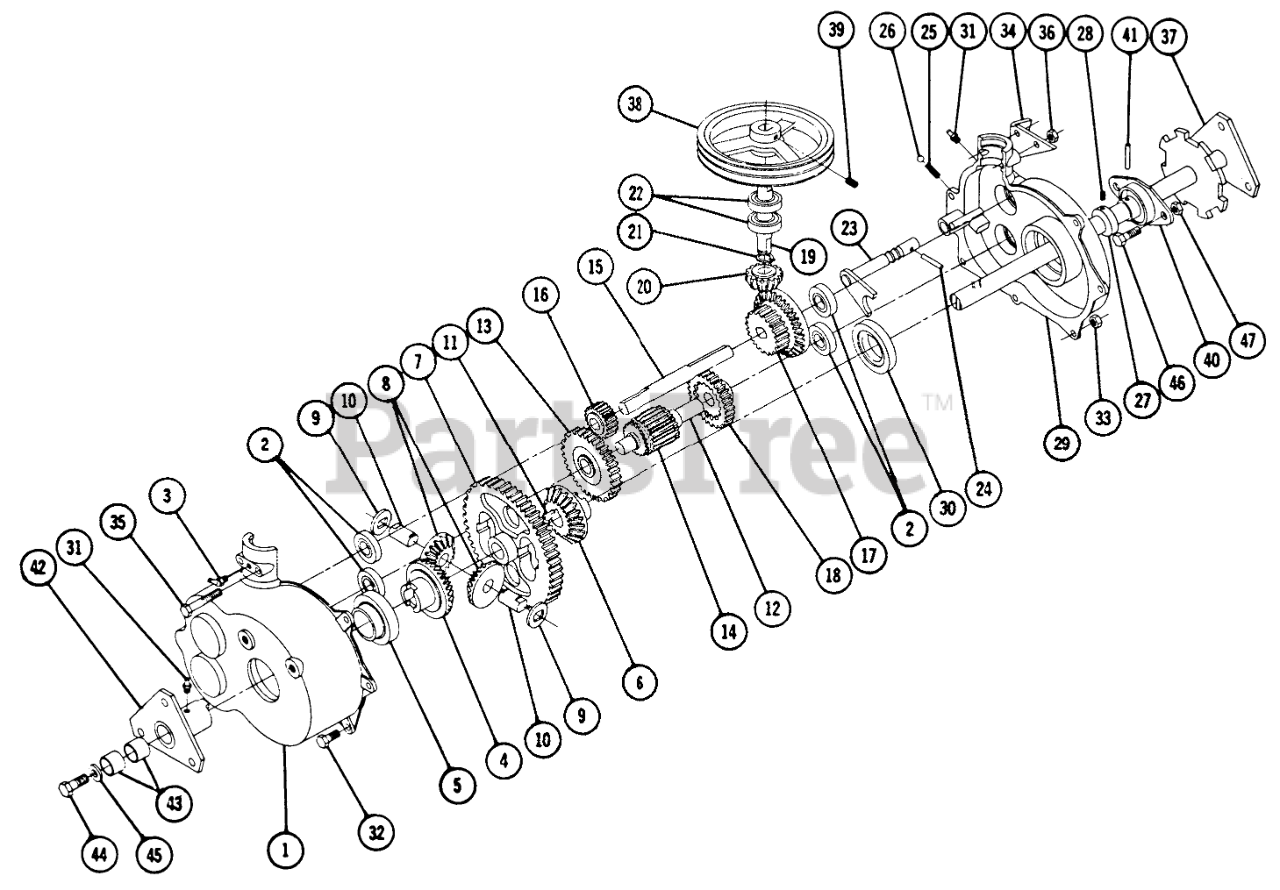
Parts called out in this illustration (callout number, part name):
3	FITTING-GREASE
11	WOODRUFF KEY
21	SNAP RING- 5/8 EXT
24	PIN-SPIROL
26	BALL-DETENT
28	Set Screw Nylok
32	Bolt, 5/16-18 X 7/8
33	Nut 5/16-18
34	Bracket-Shift Rod
35	Bolt Hex 5/6-18 X 2-1/2
36	Nut-Nylok
37	Ass-y. Axle
39	Set Screw-Nylok
41	Spirol Pin
42	Ass-y Hub Flange
43	BUSHING-BRONZE
44	Bolt 3/8-16 x 3/4 Hex
45	WASHER
46	Bolt Hex 3/8-16 x 5/8
